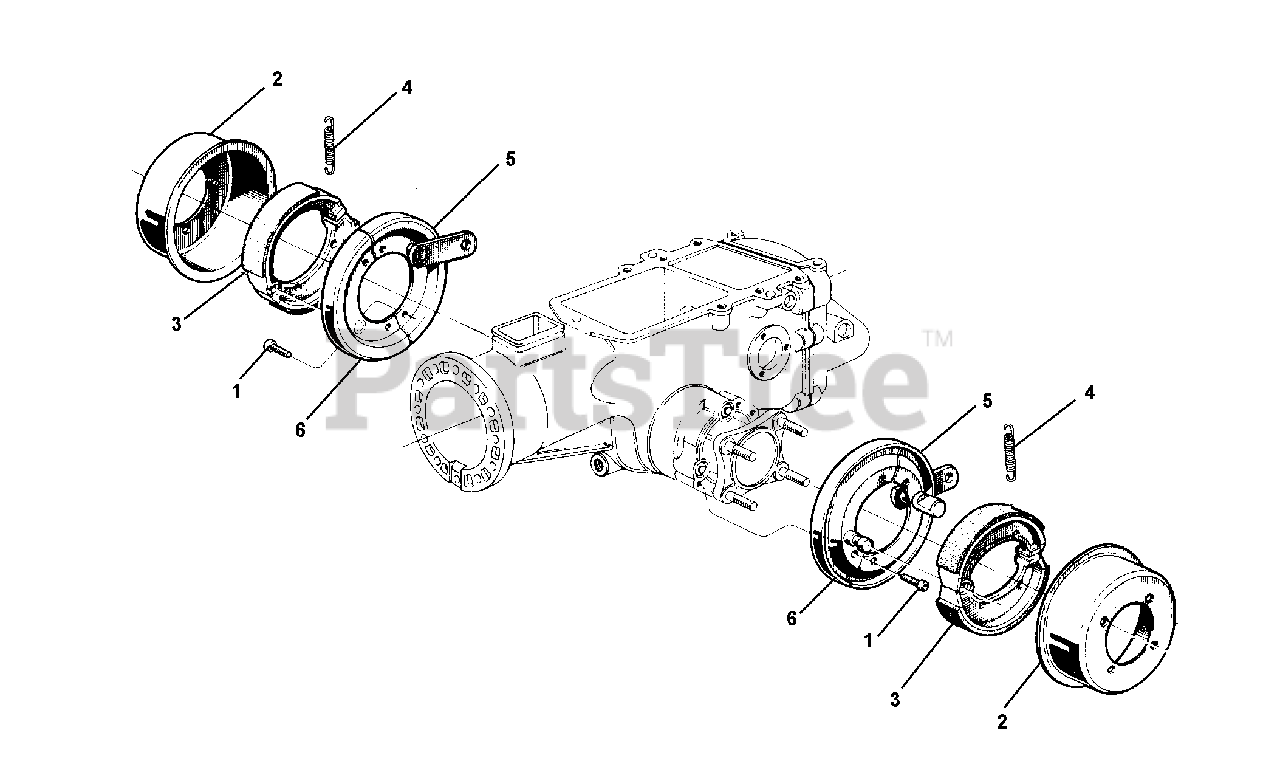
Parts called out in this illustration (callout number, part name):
1	SCREW TE CE M8 X 25
5	SEMIDISC LEVER
6	PIN HALF-DISC
